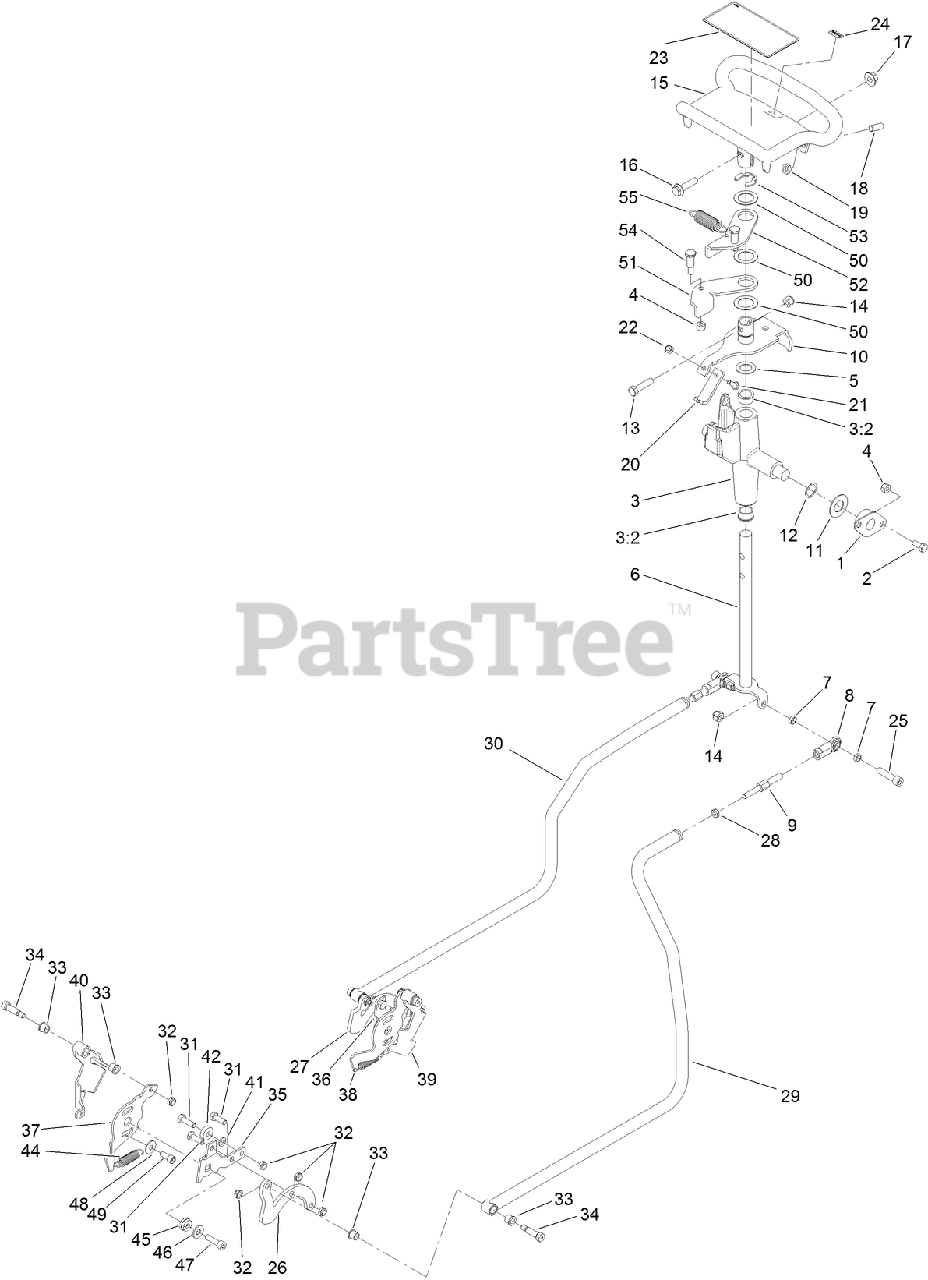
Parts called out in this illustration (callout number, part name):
1	BUSHING
2	SCREW-HH
3	CONTROL SUPPORT ASM
3:2	BEARING-FLANGE
4	NUT-LOCK, NI
5	WASHER-THRUST
6	ROD-DRIVE
7	SPACER-PLATE, RETAINING
8	JOINT-BALL END, LH
9	LINK-CONTROL, ADJUSTMENT
10	LEVER-PIVOT
11	WASHER-FLAT
12	WASHER-SPRING, WAVE
13	SCREW-HH
14	NUT-LOCK, NI
15	HANDLE-CONTROL
16	SCREW-HHF
17	NUT-FLANGE
18	SCREW-SET
19	NUT-JAM
20	PLATE-NEUTRAL
21	SCREW-HH
22	NUT-LOCK, NI
23	DECAL-TRACTION
24	DECAL
25	SCREW-HSH
26	PLATE-CONTROL, LH
27	PLATE-CONTROL, RH
28	NUT-JAM
29	LH CONTROL ROD ASM
30	RH CONTROL ROD ASM
31	SCREW-HH
32	NUT-LOCK, NI
33	BUSHING-FLANGE
34	BOLT-SHOULDER
35	PLATE-ARM, RETURN, LH
36	PLATE-ARM, RETURN
37	PLATE-BASE, LH
38	PLATE-BASE, RH
39	PIVOT-RH
40	PIVOT-LH
41	WASHER-LOCK
42	BEARING-BALL
44	SPRING-EXTENSION
45	LOCK-TRUNION
46	WASHER-FLAT
47	SCREW-HSH
48	WASHER-BELLEVILLE
49	SCREW-HSH
50	WASHER-PLAIN
51	LEVER-RETURN, RH
52	LEVER-RETURN, LH
53	RING-RETAINING
54	SCREW-SHOULDER
55	SPRING-EXTENSION
